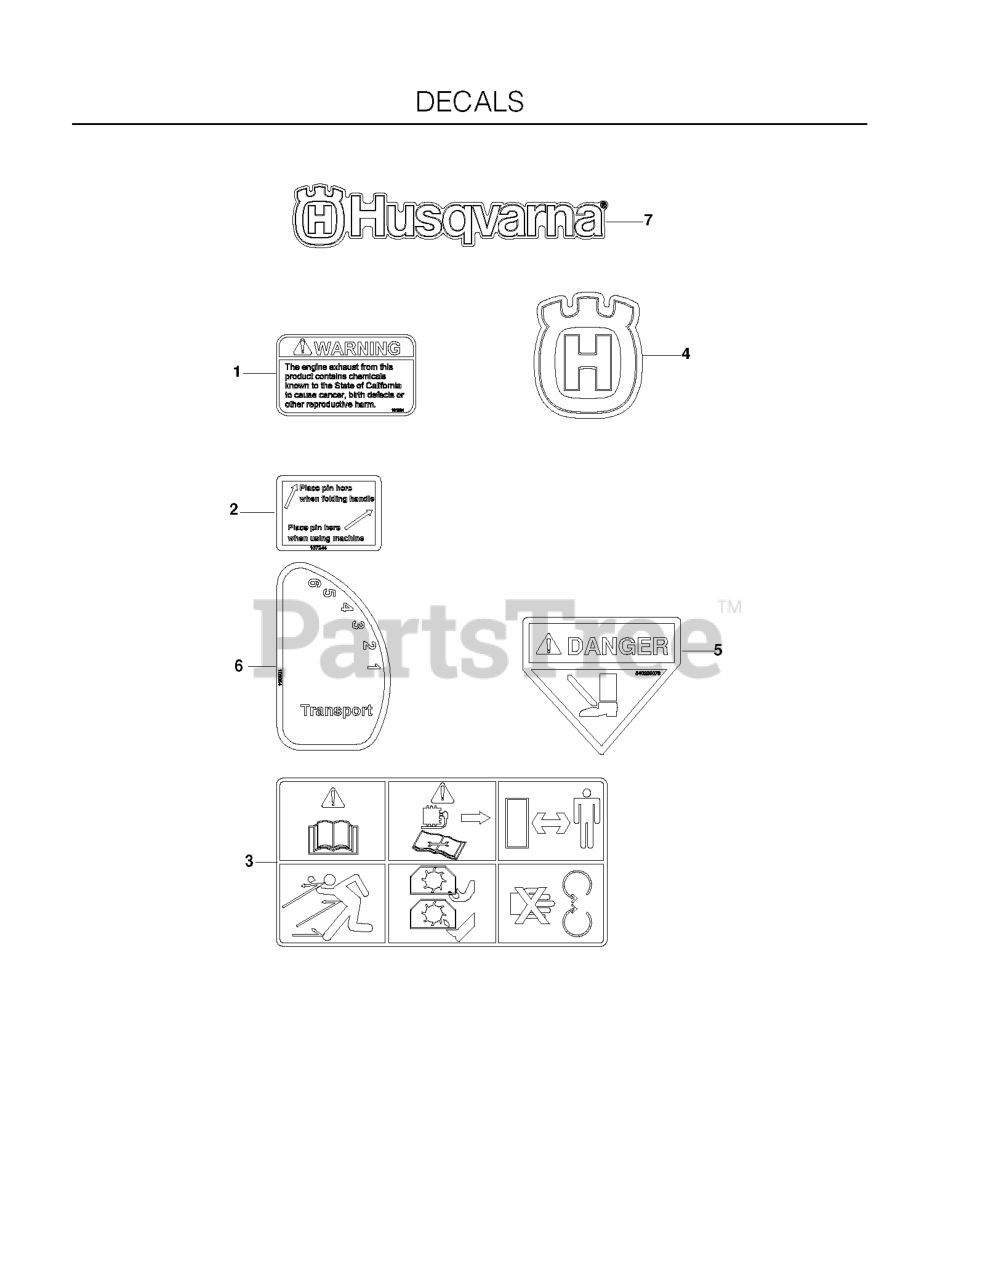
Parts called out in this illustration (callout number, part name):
1	DECAL, PROP. 65
2	DECAL, HANDLE PIN
3	DECAL, SAFETY GRAPHICS
4	DECAL, CROWN H 70MM
5	DECAL, FOOT DANGER
6	DEPTH DECAL
7	DECAL.HOOD.LOGO.ORANGE.HUSQVAR
